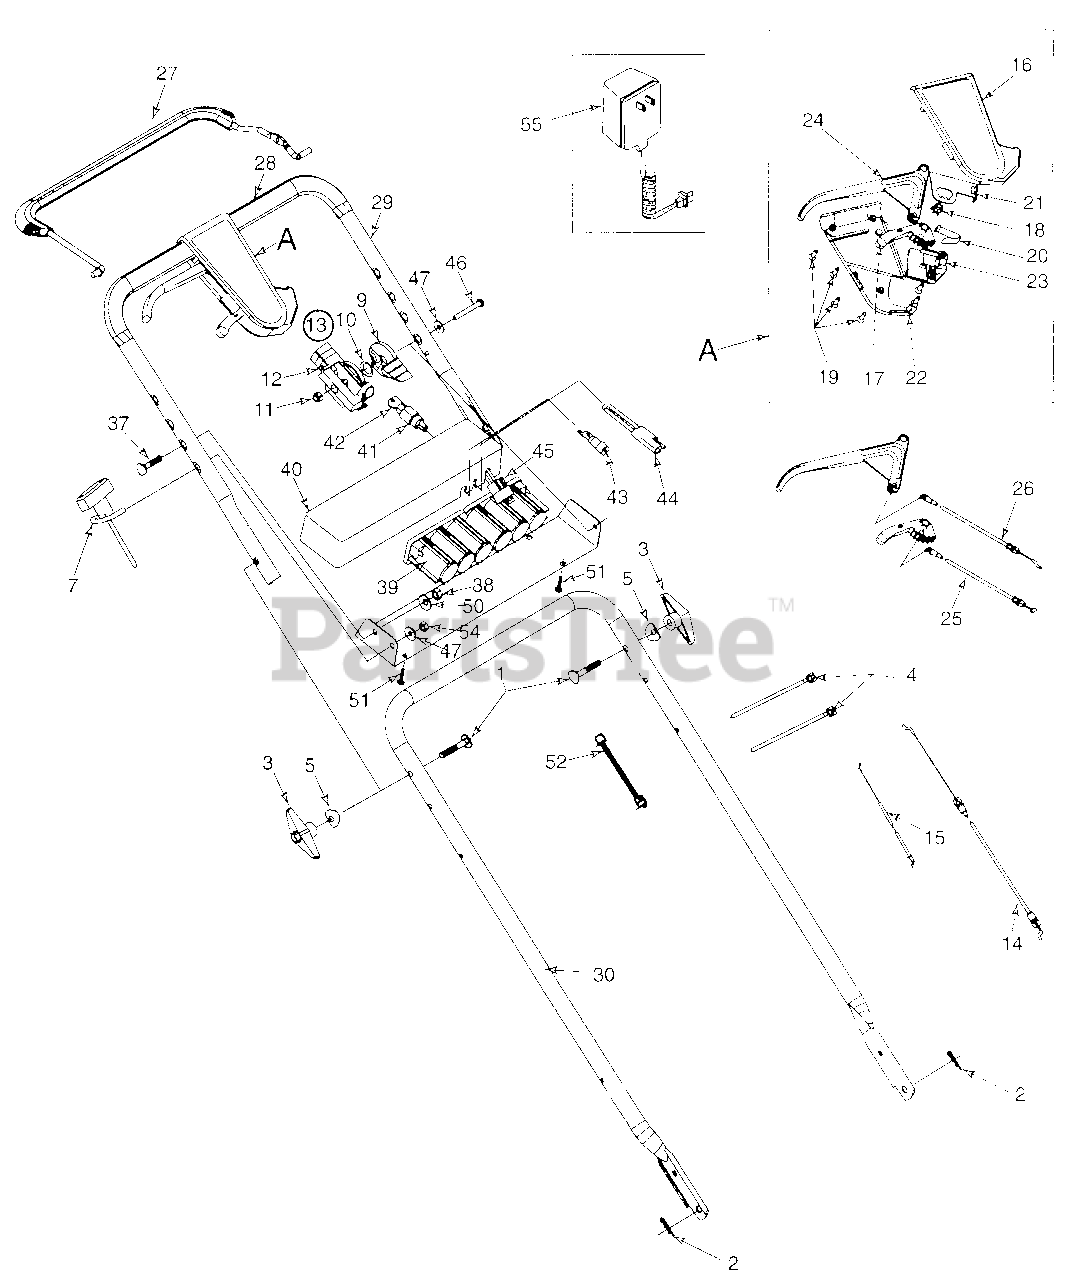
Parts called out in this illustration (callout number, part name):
1	Bolt Cur. Carr. 5/16-18 x 2.0
2	Cotter Pin .072 x 1.12 Lg.
3	Knob Ass'y Wingnut 5/16-18
4	Strap 4.3 Lg.
5	Wash. Sad. .320 ID x .830 OD
9	Throttle Lever
10	Spring Wash.Curved
11	Nut 1/4-20 Top Locknut Insert
12	Housing, Throttle
13	Throttle Control
14	Control Cable 47" Lg.
15	Cable Throttle 60" Lg.
16	Upper Control Housing
17	6 Speed Shift Lever
18	Gear Insert
19	C Sunk Tap Screw #10 x .75 L
20	Shift Lever Spring
21	6 Spd. Rack Cable Brkt.
22	Lower Control Housing
23	Cable Mounting Cap
24	Control Lever
25	6 Spd. Cable
26	S.P. Cable
28	Foam Grip
29	Upper Handle
37	Cur. Carr. Bolt 5/16-18 x 1" Lg.
38	Hex Nut 5/16-18 Thd.
39	Battery Pack - 12 Volt
41	Ignition Switch
42	Ignition Key
43	Fuse Holder
44	Plug
45	Wire Harness
46	Hex Bolt 1/4-20 x 2" Lg.
47	Bell Wash 1/4" I.D.
51	Truss Mch. Tap Scr. 1" Lg.
52	Harness Ext.
54	Hex Nut 1/4-20
55	Battery Charger
